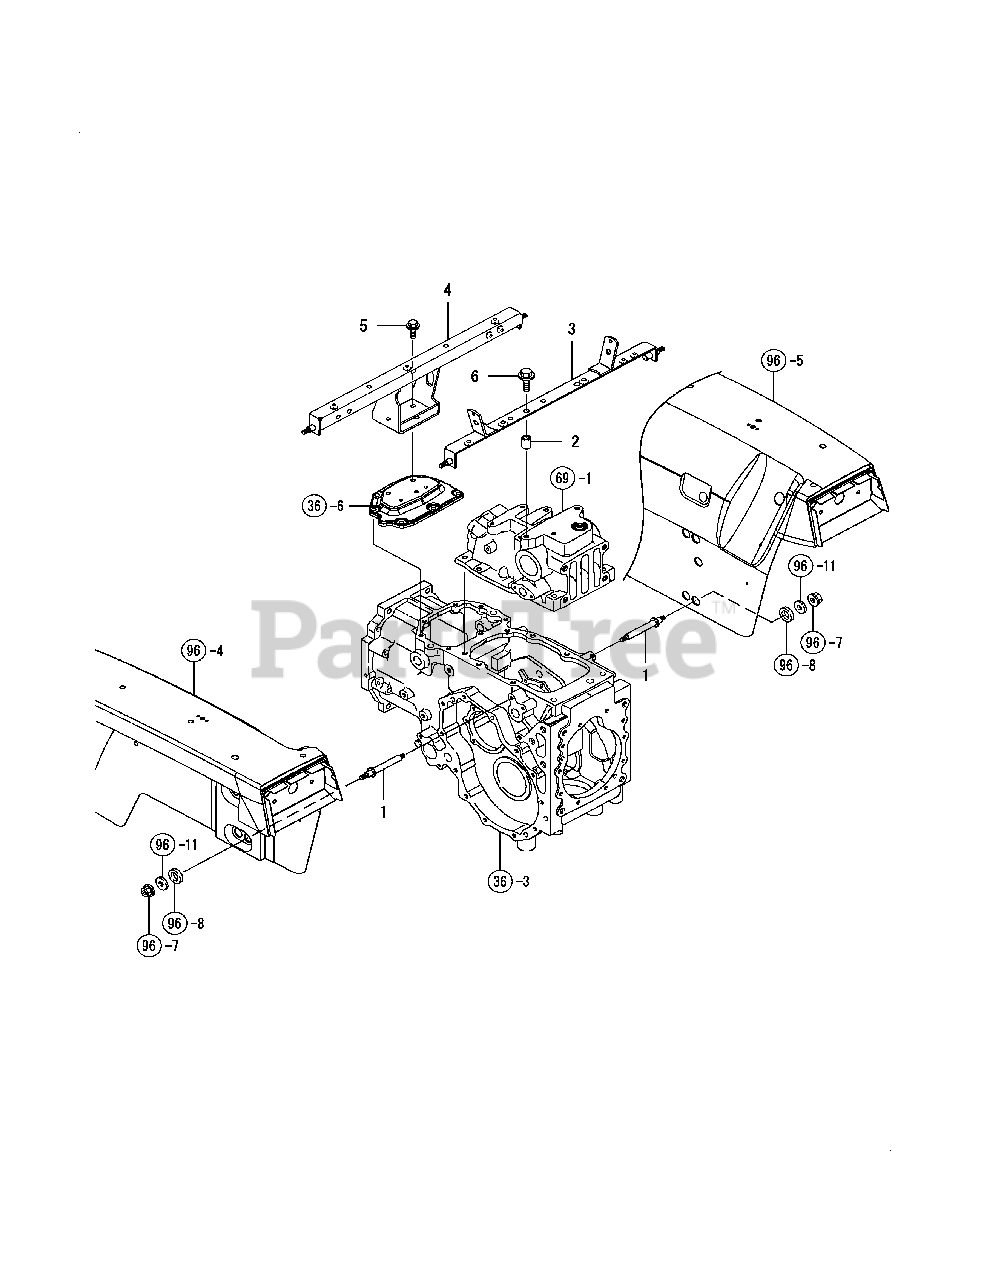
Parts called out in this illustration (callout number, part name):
3	BRACKET, FENDER R.H
5	BOLT M 8X 16 PLATED
6	BOLT M10X 40 PLATED
